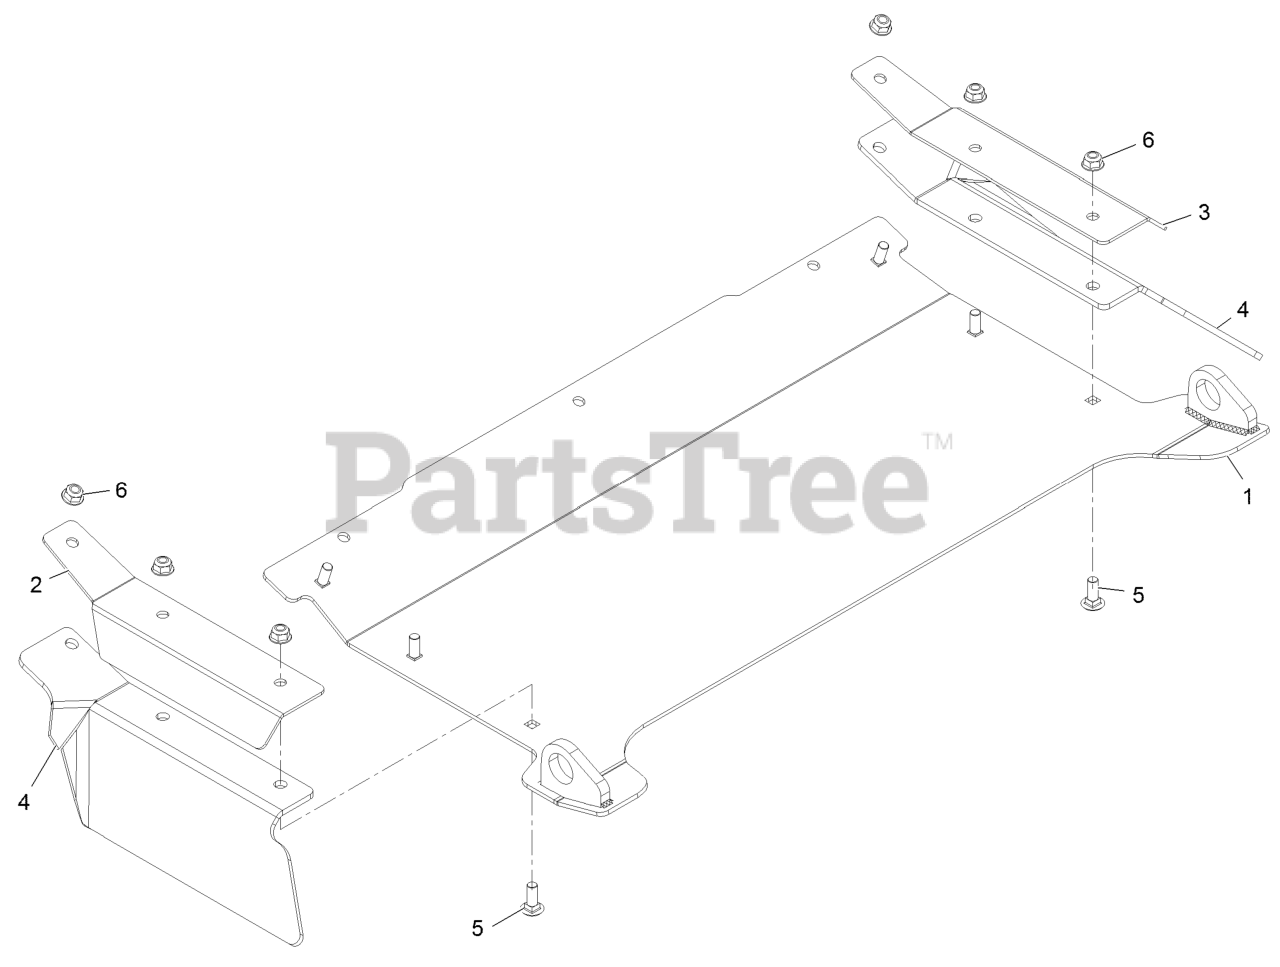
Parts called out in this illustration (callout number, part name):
2	BRACKET-FLAP, LH
3	BRACKET-FLAP, RH
4	FLAP-RUBBER
5	SCREW-CARR
6	NUT-HF, NI
